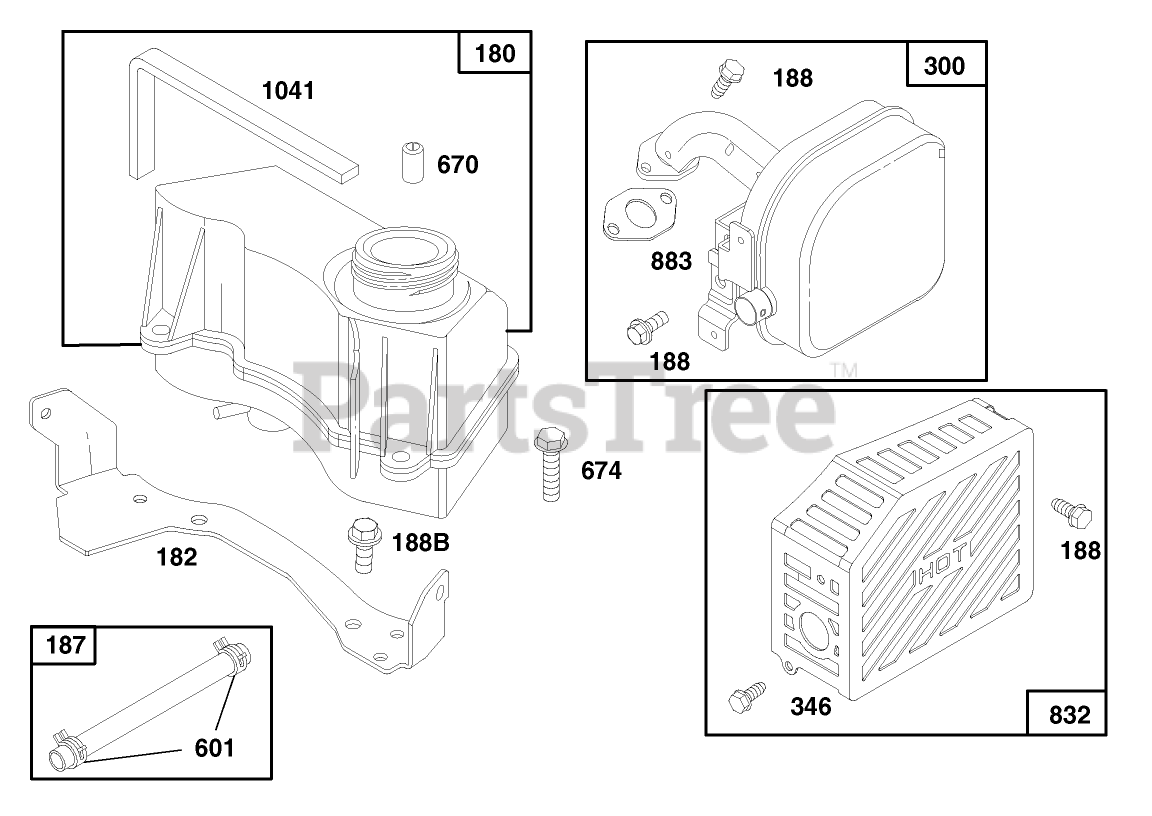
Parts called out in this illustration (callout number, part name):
180	TANK ASSY - FUEL
187	BRIGGS 296004
300	MUFFLER - EXHAUST
670	SPACER
674	SCREW - HEX HEAD
